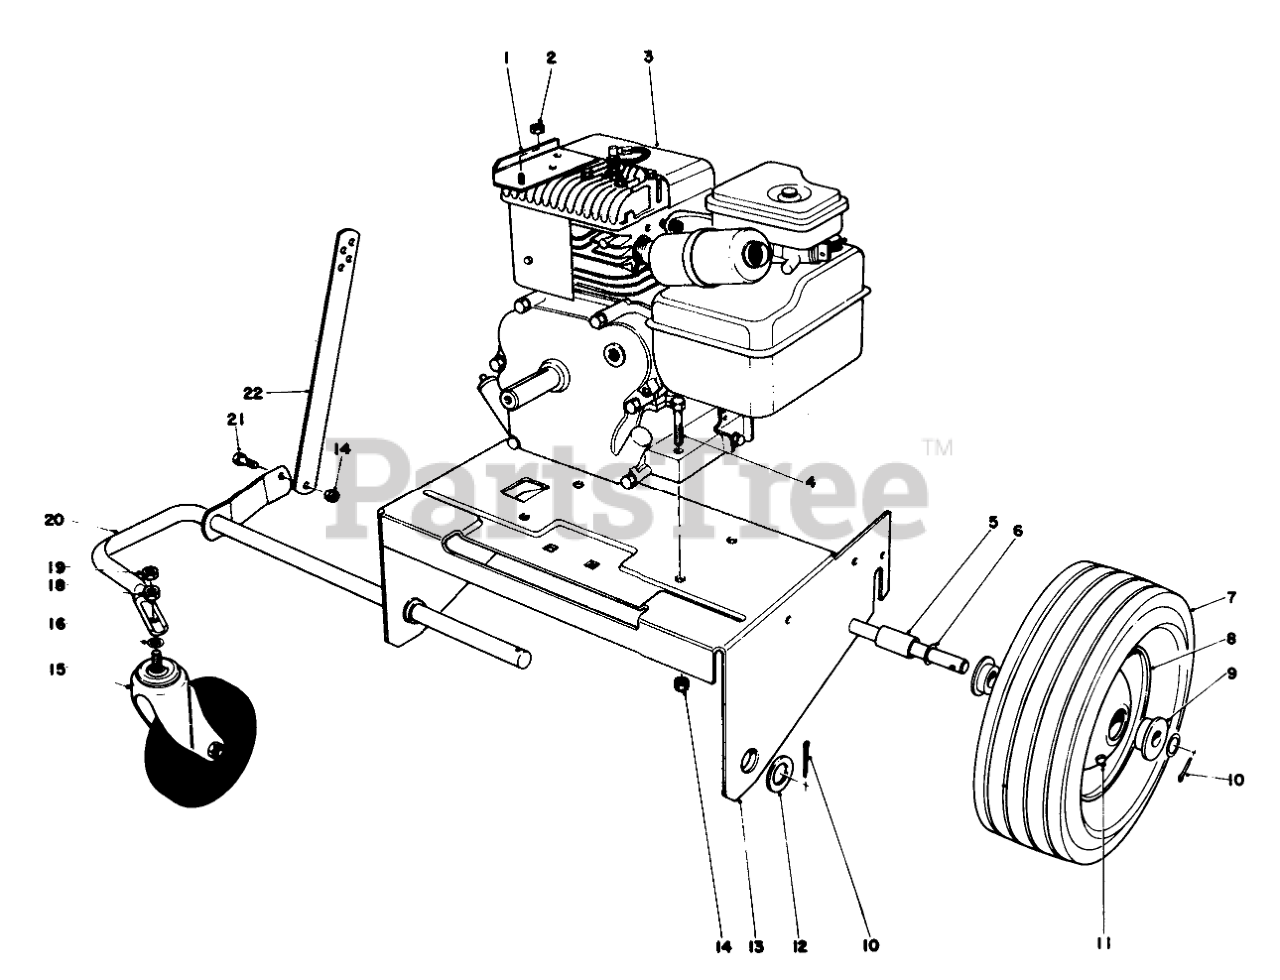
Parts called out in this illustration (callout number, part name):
1	MOUNTING BRKT WA
2	NUT-LOCK, NI
3	Engine
4	SCREW-HH
5	SPACER-AXLE
6	WASHER
7	3.50X10 SEMIPNEU TIRE
8	Rim
9	BUSHING
10	PIN-COTTER
11	FITTING-GREASE
12	WASHER-FLAT
13	BLWR ENG MTG PLT WA
14	NUT-LOCK, CONE
15	CASTER
16	WASHER-LOCK/INT
18	NUT-HH
19	1/2-13 CONELOCK NUT
20	FRT WHL SUPPORT WA
21	SCREW-HH
22	Bar Height Adjustment
